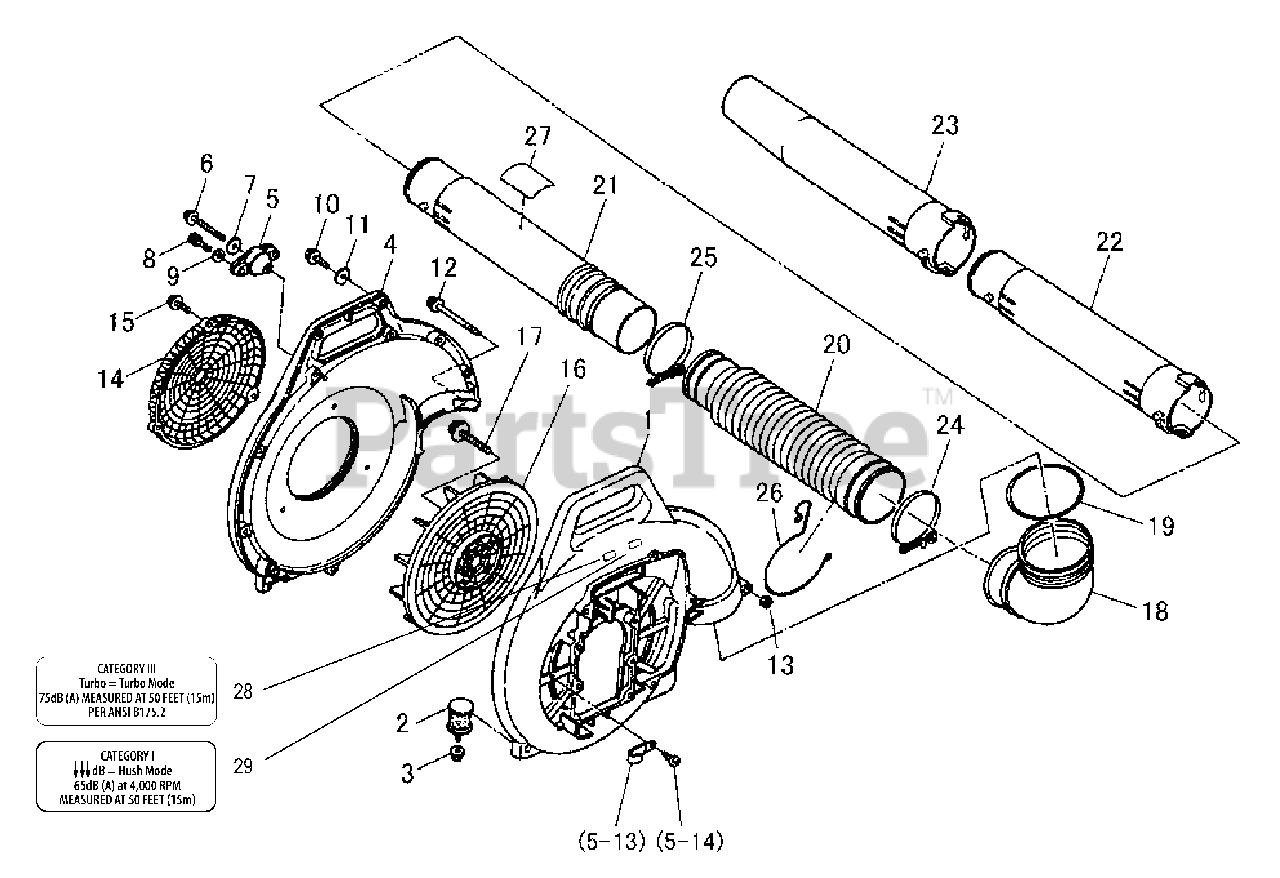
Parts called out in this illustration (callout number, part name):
1	COVER, FAN - OUTER
2	CUSHION
3	NUT - 6 -- FLANGE
4	COVER, FAN - LEFT
5	CUSHION
6	BOLT - 5 -- TAPPING
7	COLLAR - 25X5.5X2
8	SCREW - 5X16
9	COLLAR
10	BOLT - 5X20
11	WASHER - 5
12	SCREW - 5X70
14	COVER, INTAKE
15	BOLT - TAPPING
16	FAN
17	BOLT - 6X40
18	ELBOW
19	O-RING
20	FLEXIBLE PIPE
21	JOINT, PIPE
22	PIPE
23	NOZZLE
24	CLAMP
25	CLAMP
26	CLAMP
27	LABEL - TRADE
28	LABEL - NOISE 75dB(A) CAT III
29	LABEL - NOISE 65dB(A) CAT I
